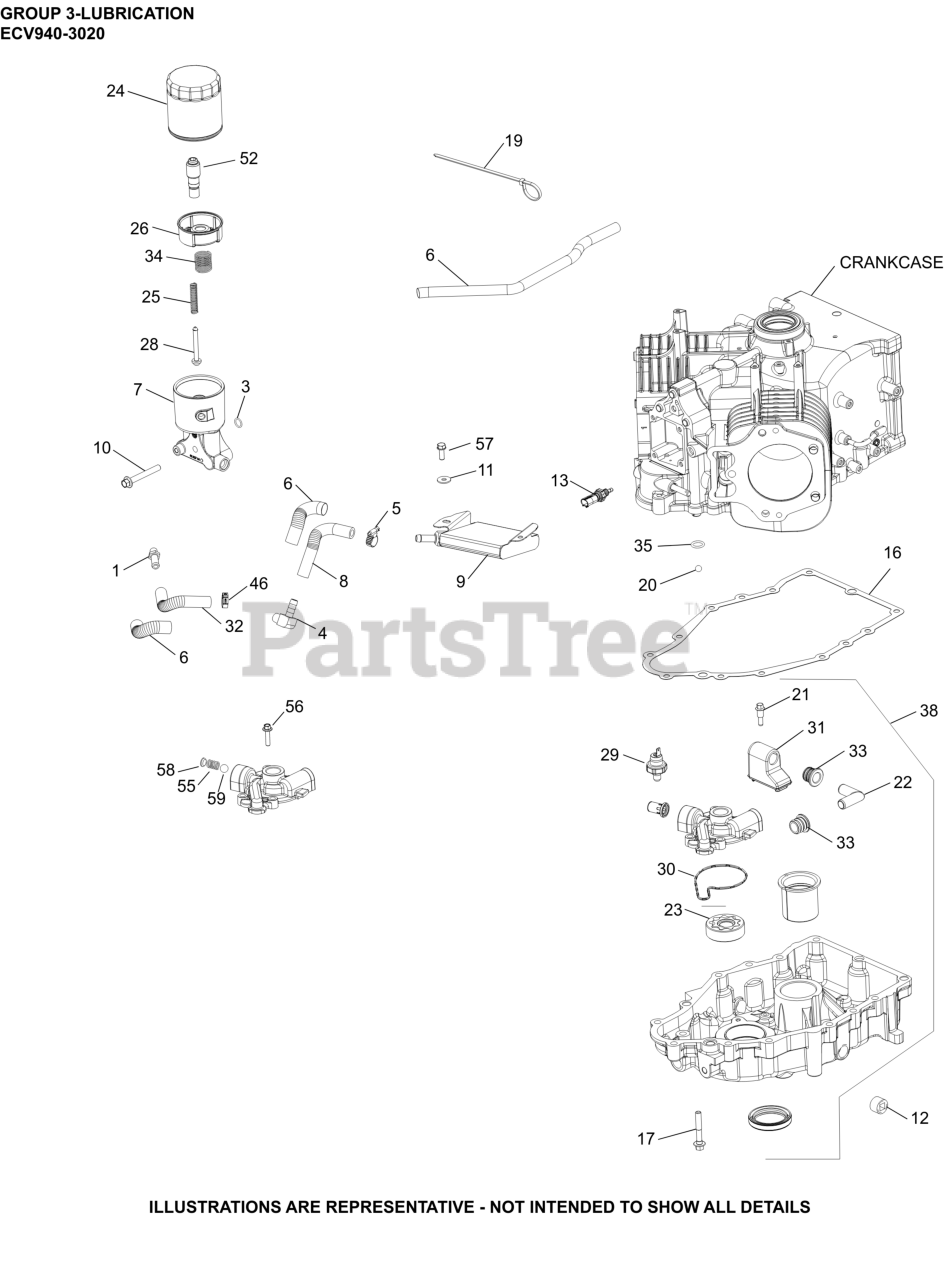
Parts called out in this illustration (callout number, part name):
1	FITTING, HOSE TO PIPE
3	O-RING, OIL PICK-UP
4	FITTING, 90 DEG. BARBED
6	SLEEVE, ANTI ABRASION-USE 25 431 12-S
7	HOUSING, VERTICAL OIL FILTER - MACHINED
8	HOSE, OIL SUPPLY
9	COOLER, OIL ASSEMBLY
10	SCREW, FLG M8X1.25X60
11	WASHER, FLAT 1/4"
12	PLUG, PIPE 1/2 NPTF SQ CTSK
13	SENSOR, TEMPERATURE
16	GASKET, OIL PAN
17	SCREW, HEX FLANGE
19	TIE, CABLE
20	KIT, CHECK BALL
21	SCREW, SHD THD FRM M6X.0X6.5
22	TUBE, OIL PICK-UP
23	PUMP ASSEMBLY, OIL/GEROTOR
24	OIL FILTER
25	SPRING, OIL FILTER VALVE
26	CUP, OIL FILTER ASSEMBLY
28	VALVE, OIL FILTER
29	SWITCH, OIL PRESSURE
30	O-RING, OIL PUMP HOUSING
31	HOUSING, OIL PICK-UP ASSEMBLY
32	HOSE, OIL RETURN
33	SEAL, PICK-UP TUBE
34	SPRING, OIL FILTER CUP
38	KIT, OIL PAN
46	CLAMP, HOSE OETIKER
52	NIPPLE, OIL FILTER ASSEMBLY
55	SPRING, COMPRESSION
56	SCREW, HEX FLANGE M6 X 1
57	SCREW, HEX HEAD
58	PLUG, CUP
59	PRESSURE RELIEF BALL
NI	SEAL, OIL (LEFT-HAND HELIX, PTO)
